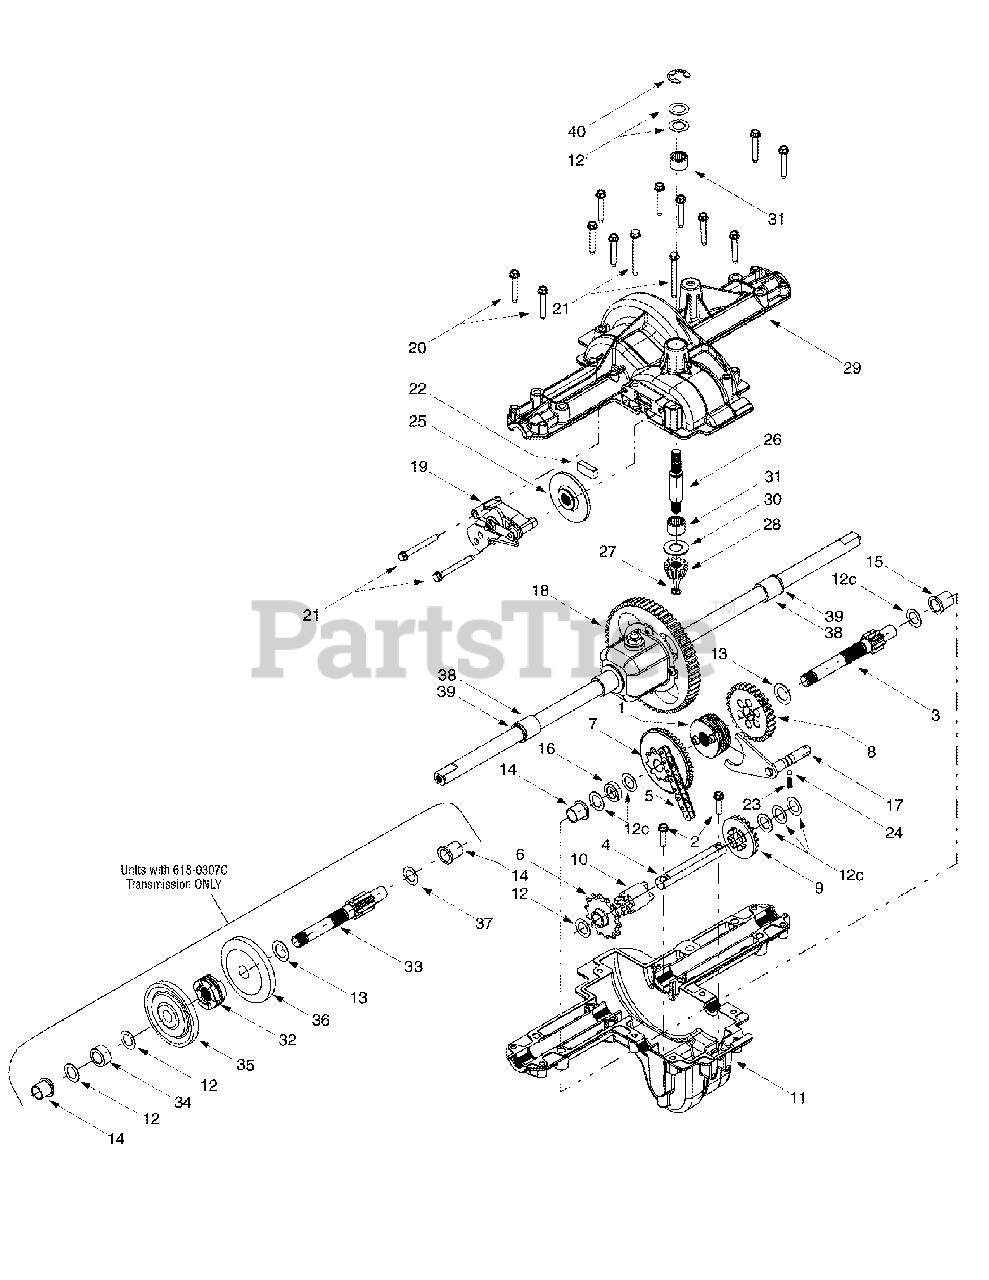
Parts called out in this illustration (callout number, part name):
1	Clutch Collar
2	Self-tapping Screw, 1/4-20 x 1.0
3	Drive Shaft
4	Counter Shaft
5	22-link Chain, #420
6	14-tooth Sprocket
7	Sprocket Bevel Gear, 42/10
8	29-tooth Spur Gear
9	20-tooth Spur Gear
10	Counter Shaft Coupling
11	Lower Housing
12	Flat Washer, 5/8 x 1.0 x .030
12	Flat Washer, 5/8 x 1.0 x .040
12C	Flat Washer, 5/8 x 1.0 x .020
13	Flat Washer, .70 x 1.125 x .031
14	Flange Bearing, 5/8 x 3/4 x 3/4
15	Flange Bearing, 5/8 x 3/4 x 15/16
16	Spacer, .635 x 1.0 x .27
17	Detent Shaft Assembly
18	Differential Assembly
19	Brake Assembly
20	Self-tapping Screw, 1/4-20 x 1.625
21	Self-tapping Screw, 1/4-20 x 2.375
22	Brake Pad
23	Compression Spring
24	Detent Ball
25	Brake Disc
26	Input Shaft
26	Input Shafts
27	Retaining Ring, .394
27	Retaining Ring, .437
28	12-tooth Bevel Pinion
28	14-tooth Bevel Pinion
29	Upper Housing Kit
30	Thrust Washer, .63 x 1.24 x .062
30	Thrust Washer, .635 x 1.25 x .042
31	Needle Bearing, .625 x .875
32	Clutch Collar
33	Drive Shafts
34	Spacer, .633 x 1.0 x .513
35	42-tooth Bevel Gear
36	42-tooth Bevel Gear
37	Thrust Washer, 1.0 x .632 x .0
38	Sleeve Bearing, .75 x .1.0 x 1.0
39	Seal, .75 x 1.0 x .125
40	E-ring..75
